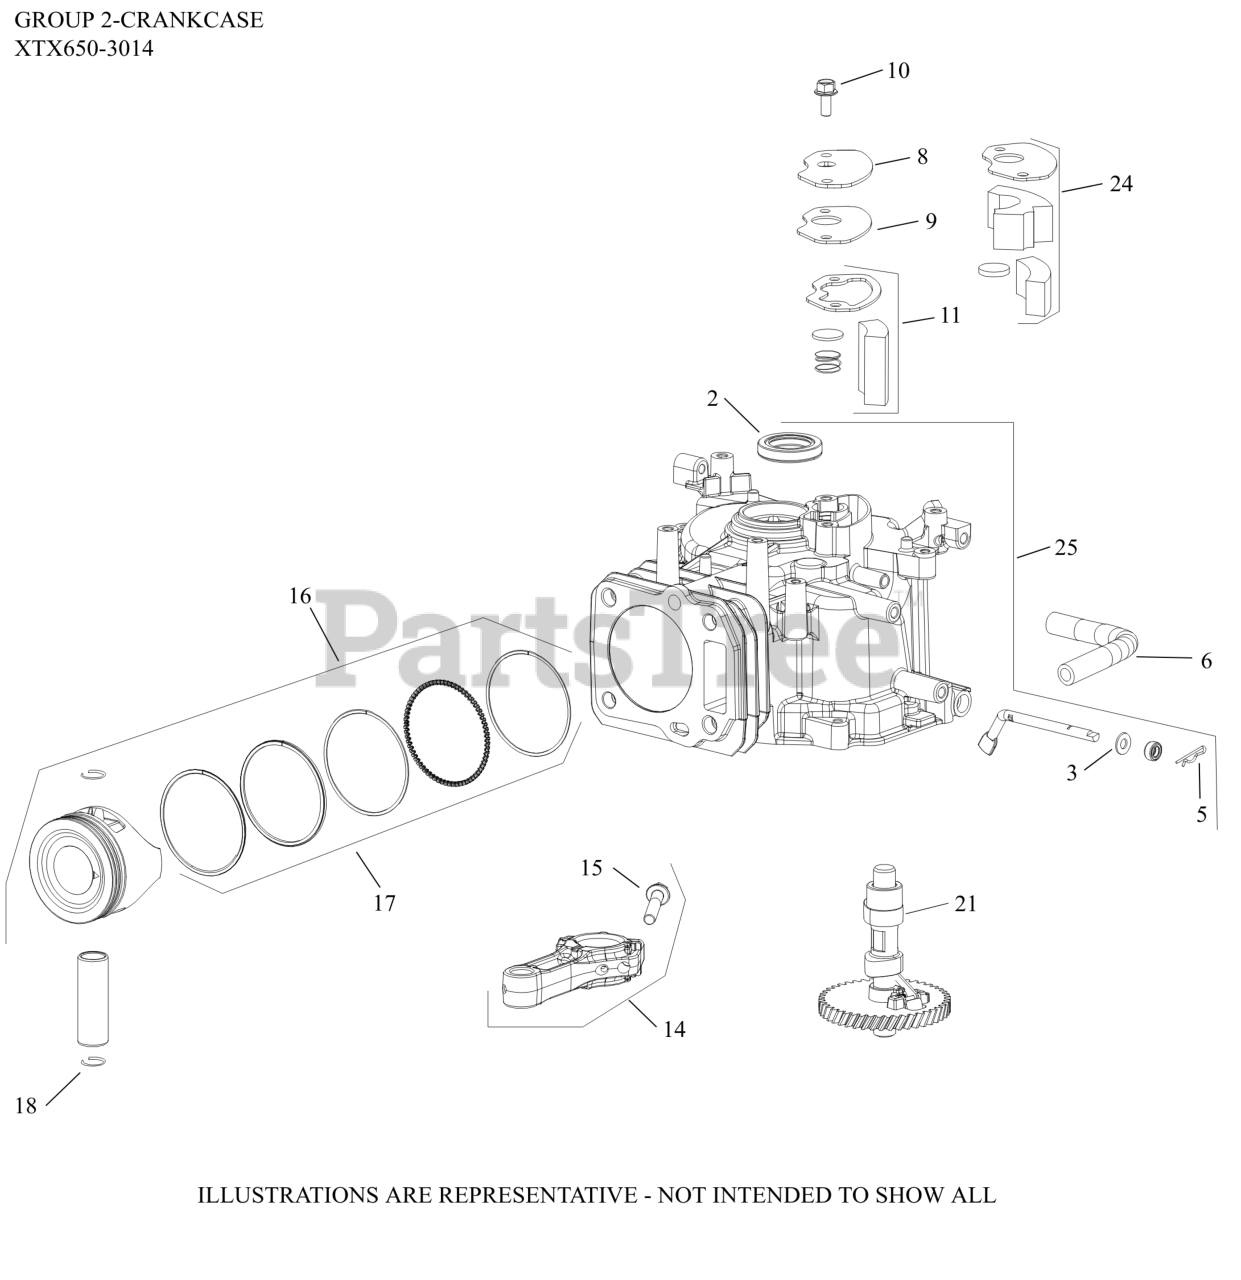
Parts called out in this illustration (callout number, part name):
2	SEAL, CCASE/FLYWHEEL
3	WASHER, FLAT (DIA 13mm O.D.)
5	CLIP, GOVERNOR SHAFT
6	HOSE, BREATHER
8	COVER, BREATHER
9	GASKET, BREATHER COVER
10	SCREW, HEX FLANGE (M6)-USE 25 086 433-S
11	KIT, BREATHER FILTER
14	ROD, CONNECTING ASSEMBLY
15	SCREW, HEX FLANGE (M7)
16	PISTON ASSEMBLY (SERVICE)
17	RING SET (SERVICE) (XT149)
18	RETAINER, PISTON PIN
21	CAMSHAFT, ASSEMBLY
24	KIT, BREATHER FILTER
25	KIT, CRANKCASE
